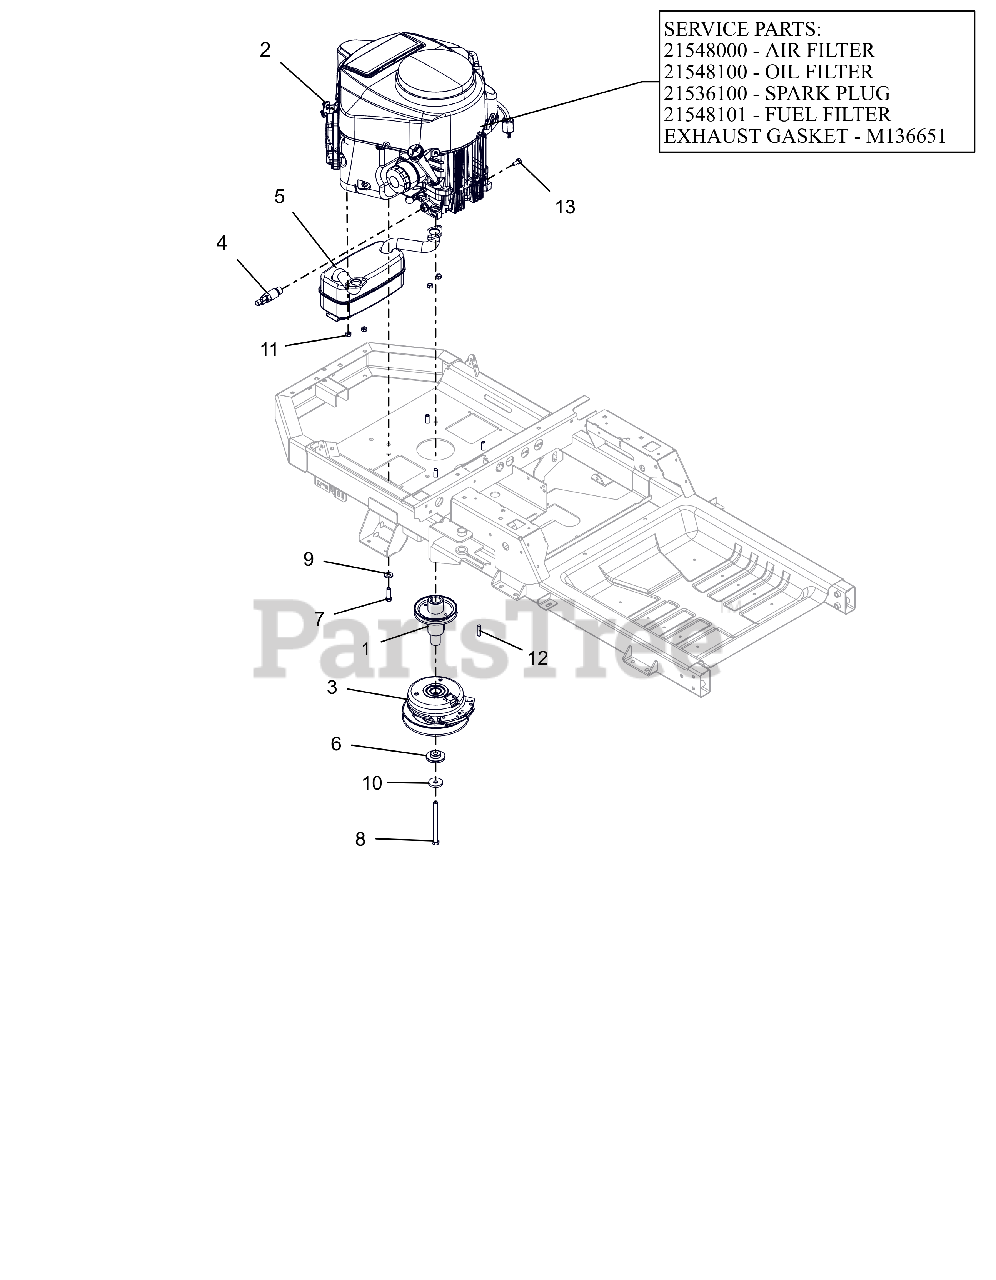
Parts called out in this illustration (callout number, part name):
1	WLDMT, DRIVE SHEAVE (LG XL)CZC
2	ENGINE, KAWASAKI FR730 24HP
2	AIR FILTER, KAWASAKI FR
2	OIL FILTER, KAWASAKI FR
2	PLUG, SPARK
2	FUEL FILTER-KAWASAKI FR
2	GASKET, MUFFLER #
3	CLUTCH,105FTLB MONOPOLE 6.83"
4	DRAIN, OIL M20X2.5
5	MUFFLER, KAWASAKI
6	BSHG-FLG .469X1.06X.574X2.0
7	BLT-HEX.38-16X1.25 G5YZ NYTORQ
8	BLT-HEX.438-20X5 GR8 YZ NYTORQ
9	WASHER, 3/8" SPRING DISC
10	WASHER, 7/16" SPRING DISK
11	NUT-LK-TOP M8-1.25 YWZC
12	KEY-SQ .25 X 1.25 X .25 SAE
13	BLT, HEX M8-1.25X20 G8.8 ZCC
